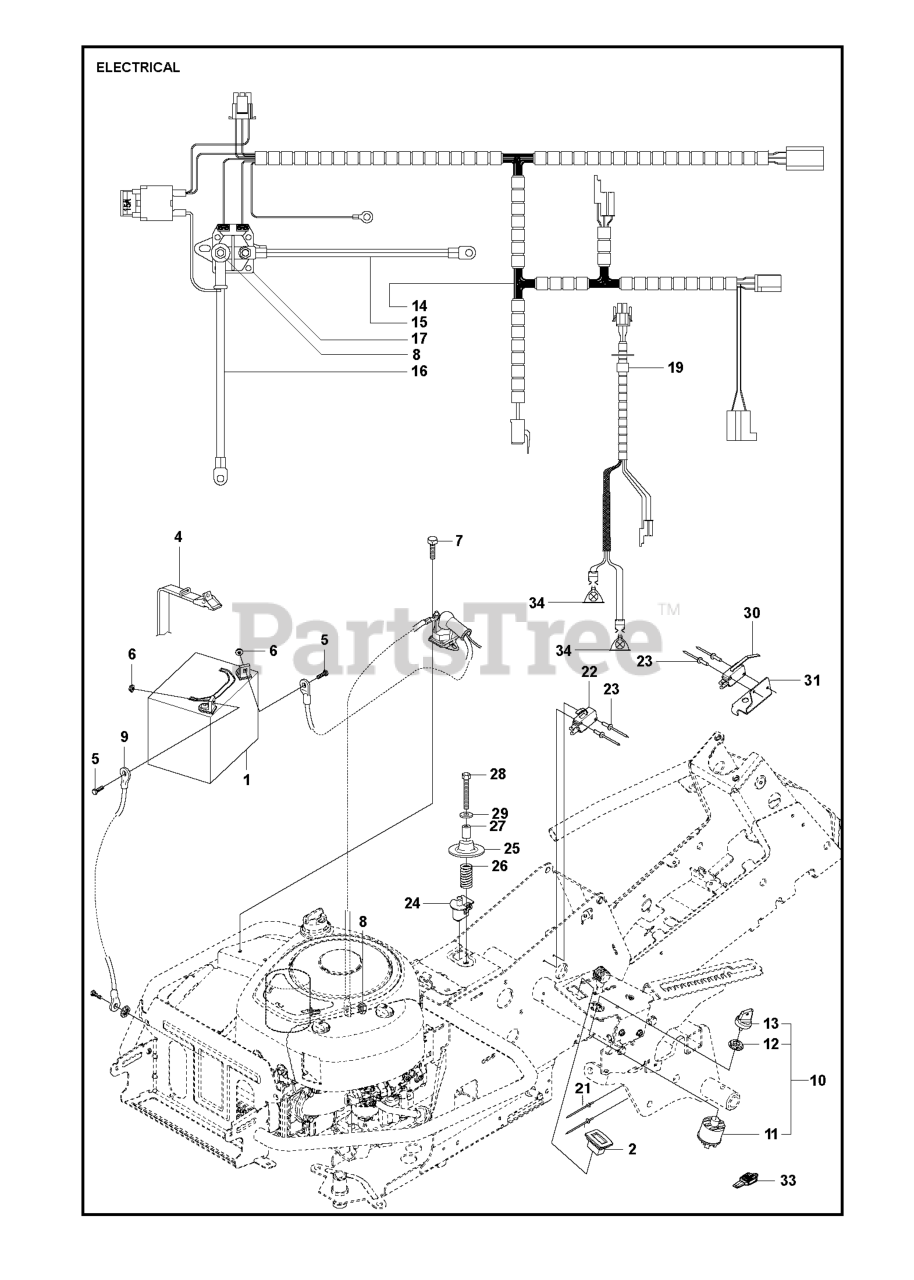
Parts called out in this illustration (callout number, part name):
2	HOUR METER
5	SCREW EHHM
10	IGNITION SWITCH
11	IGNITION SWITCH
13	IGNITION KEY
14	WIRING
16	CABLE
16	WIRE BATTERY
21	Rivet
22	SWITCH
22	MICRO SWITCH
23	RIVET
27	SPACER TUBE
28	SCREW
29	WASHER BRB 8.4X17
30	MICRO SWITCH
